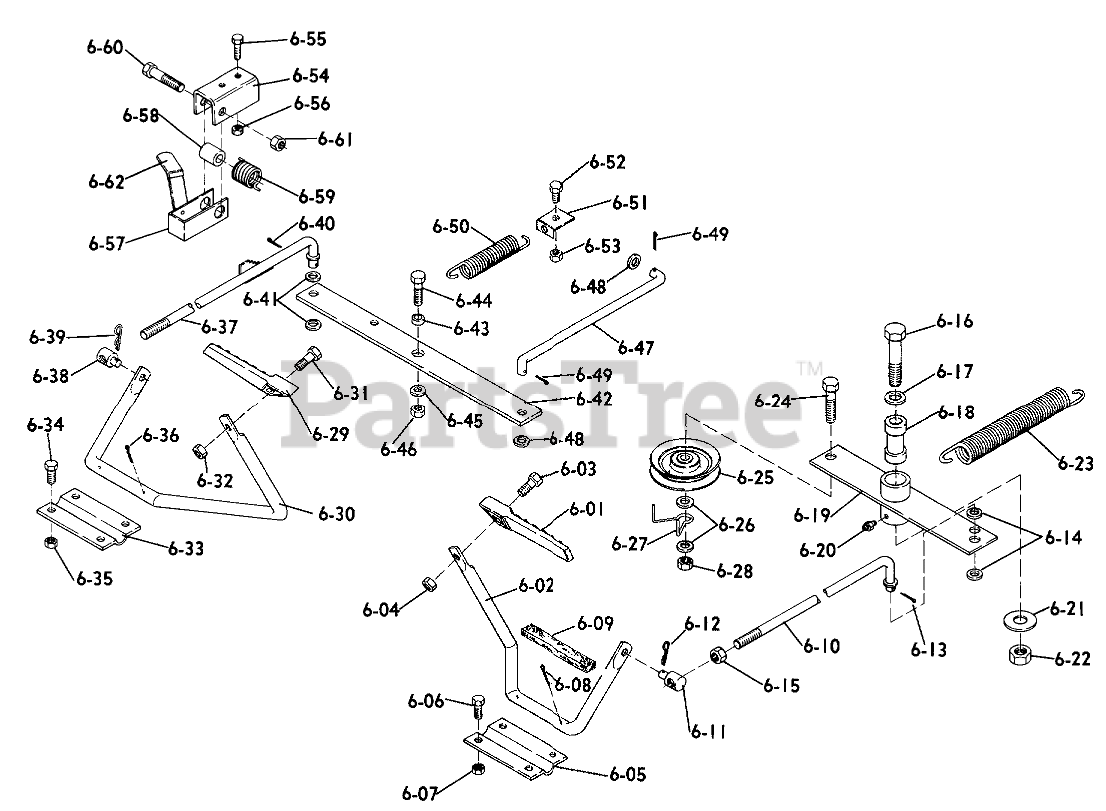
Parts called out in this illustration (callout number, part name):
6-01	Clutch Pedal
6-02	L.H. Control Arm
6-03	Bolt
6-04	NUT
6-05	Bracket
6-06	H H C S
6-07	Nut
6-09	Mat Padding
6-10	Clutch Rod Assembly
6-11	Trunnion
6-12	Hairpin Cotter
6-13	Cotter Pin
6-14	WASHER-NYLON
6-15	Nut
6-16	Bolt 1/2-13 x 2 3/4
6-17	SHIM-WASHER
6-18	Bushing
6-19	Idler Arm Assembly
6-20	Zerk
6-21	Washer
6-22	Eslok Nut
6-23	SPRING TRACTION CLUT
6-24	Bolt
6-25	PULLEY-IDLER STATION
6-26	Washer
6-27	BELT GUIDE
6-28	Nut
6-29	Brake Pedal
6-30	Control Arm
6-31	Bolt
6-32	NUT
6-33	Bracket
6-34	Bolt
6-35	Nut
6-37	Brake Rod Assembly
6-38	Trunnion
6-39	Hairpin Cotter
6-40	Pop Rivet
6-41	WASHER-NYLON
6-42	Brake Lever
6-43	Spacer
6-44	Bolt
6-45	Collar
6-46	Nut
6-47	Brake Rod
6-48	Washer
6-49	Pop Rivet
6-50	SPRING-EXTENSION
6-51	Spring Clip
6-52	H H C S
6-53	Nut
6-54	Parking Brake Bracket
6-55	Bolt, 3/8-16 x 1/2
6-56	Nut
6-57	Brake Lever Assembly
6-58	SPACER
6-59	Torsion Spring
6-60	Bolt
6-61	Nut
6-62	GRIP
